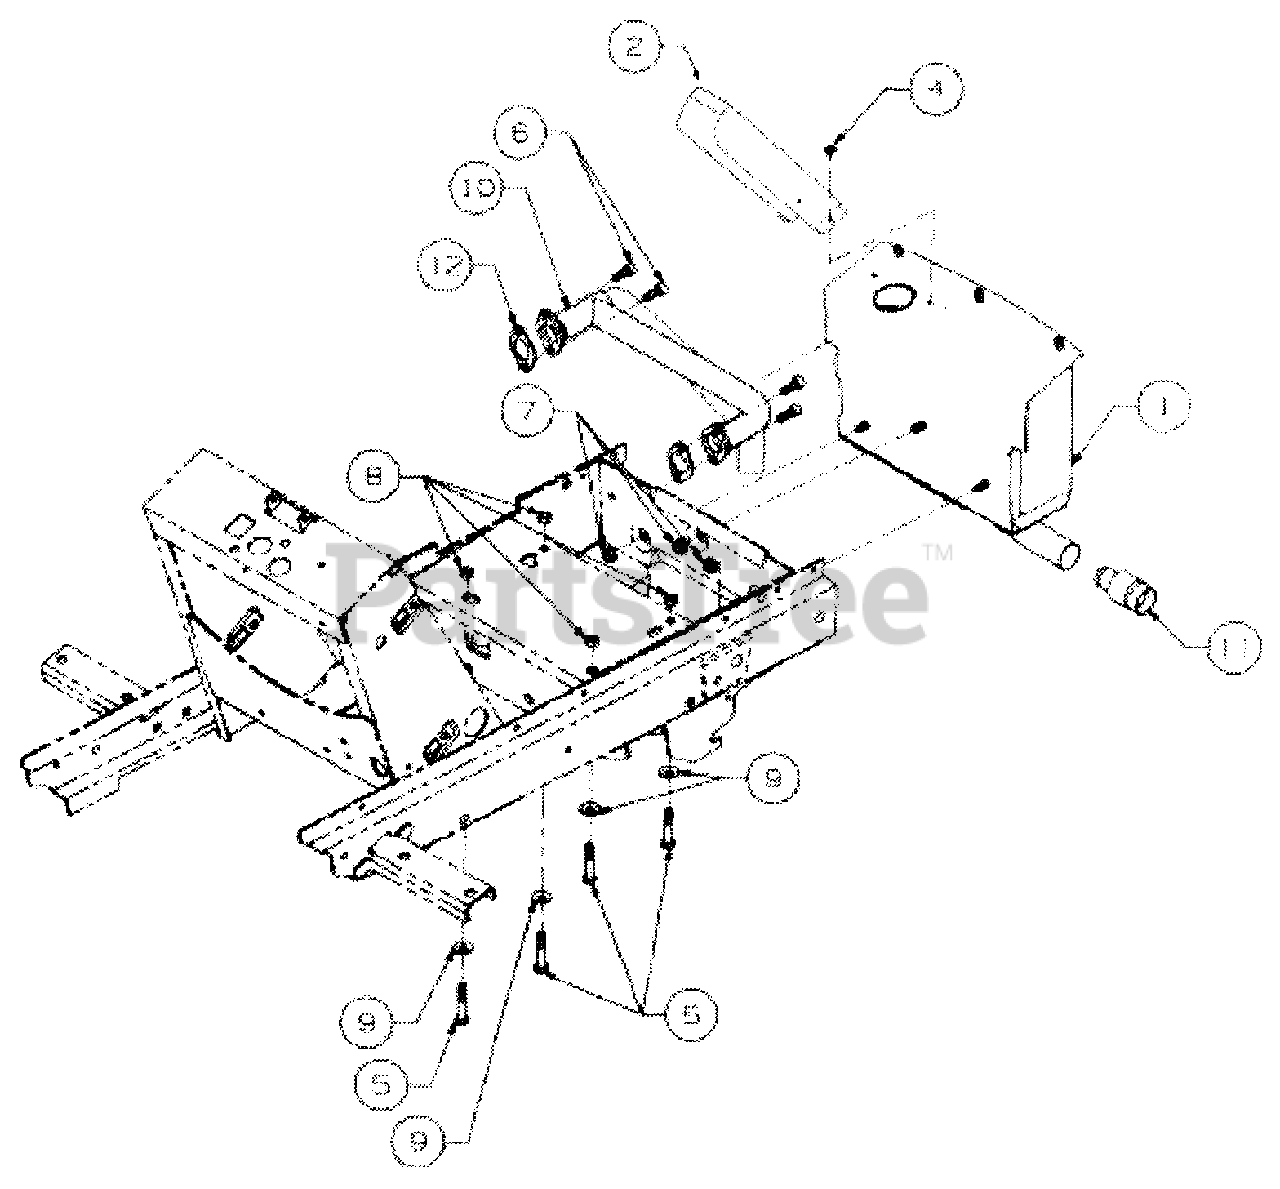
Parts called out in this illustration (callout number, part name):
1	Muffler Assembly
2	Sheild, Muffler Tube
4	Screw, Hex Wsh Hd Tap, #10-16 x .38
5	Bolt, Eng Mount, 5/16-18 x 1.75 GR5
6	Screw, Scket Hd Cap, M8-1.25 x 20mm
7	Nut, Hex Flange Lock, 5/16-18
8	Nut, Hex, 5/16-18 GR5
9	Washer, Bell, .345 x .88 x .060
10	Tube, Exhaust
11	Arrestor, Spark
12	Gasket, Exhaust
